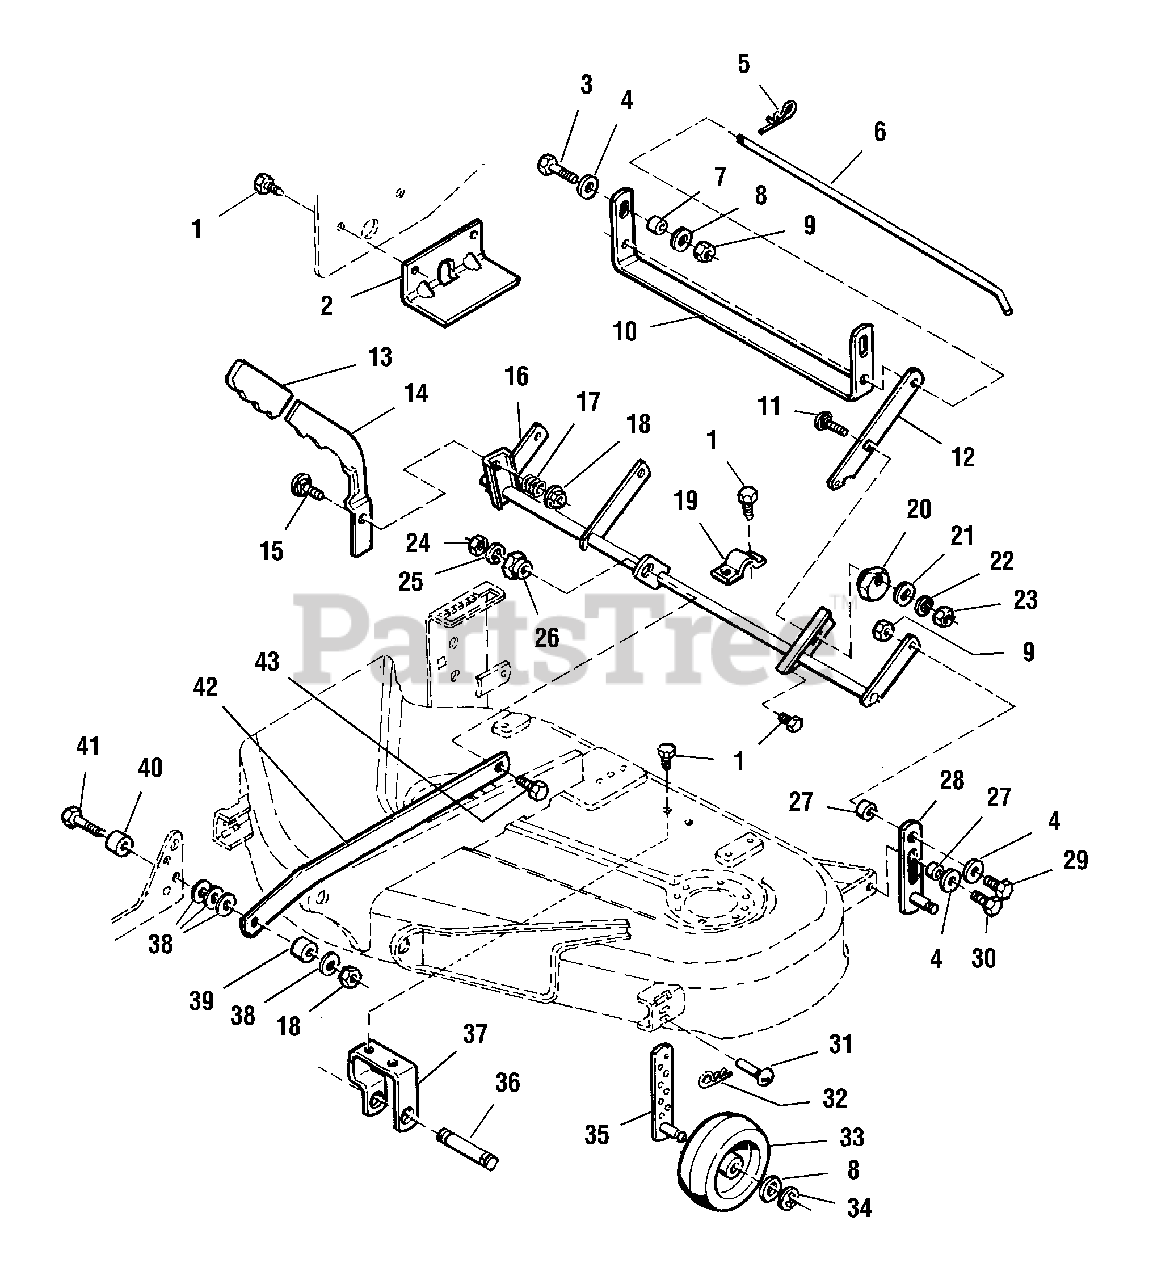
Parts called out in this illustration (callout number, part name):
1	SCREW, Taptite, 5/16 x 3/4
3	CAPSCREW, 5/16-18 x 1-1/4
5	SPRING, Clip
6	ROD, Transport
8	WASHER, 1/2
9	NUT, Lock, 5/16-18
10	U-BRACKET
11	CARRIAGE BOLT, 5/16-18 x 1-1/4
14	ADJUSTMENT ARM
15	CARRIAGE BOLT, 3/8-16 x 1-3/4
16	ROCKER ARM ASSY.
18	NUT, Flange Lock, 3/8
19	STRAP
21	WASHER, Flat, 5/16
22	LOCKWASHER, 5/16
23	NUT, 5/16-18
24	NUT, Hex, 3/8
25	LOCKWASHER, 3/8
26	NUT, Hex Adjusting, .99 DIA .687
29	CAPSCREW, 5/16-18 x 1
30	SCREW, Taptite, 5/16-18 x 1
32	CLIP, Hair
33	GAUGE WHEEL
34	E-RING, 1/2
35	ARM ASSY., Adjustable
36	SHAFT, Gauge Wheel
37	BRACKET, Gauge Wheel
38	WASHER, Flat, 3/8
41	CAPSCREW, 3/8-16 x 1-1/4
42	ARM, Pitch
43	CARRIAGE BOLT, 3/8-16 x 1-1/2
